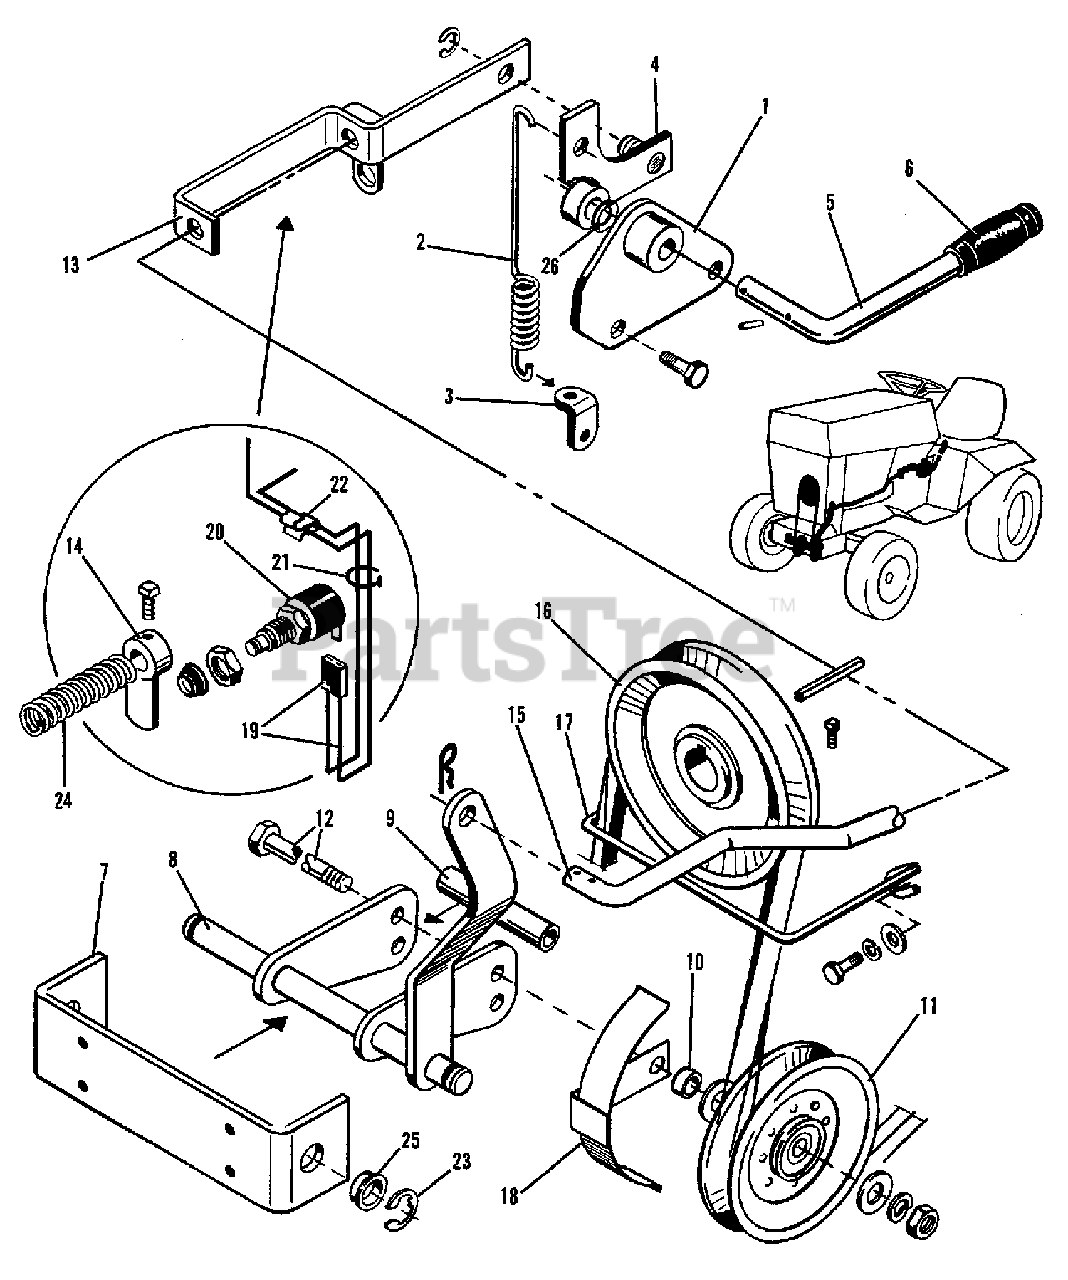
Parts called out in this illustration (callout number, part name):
1	BRACKET ASSEMBLY, P.T.O Clutch Arm
2	SPRING, Extension
3	CLIP, Spring
4	ARM ASSEMBLY, P.T.O. Clutch
4	RING, Snap
5	LEVER, Clutch, P.T.O.
5	PIN, Roll, 3/16 x 1
6	GRIP, Handle
7	BRACKET, Idler Support
7	CAPSCREW, 5/16 NC x 3/4
7	LOCKWASHER, 5/16
7	NUT, Hex, 5/16 NC
8	CLEVIS ASSEMBLY, P.T.O. Idler
9	SPACER, Idler
11	PULLEY, Idler
12	CAPSCREW, 3/8 NC x 6-1/4
12	WASHER, Plain, 7/16 x 1 x 14 Ga.
12	LOCKWASHER, 3/8
12	NUT, 3/8 NC
13	GUIDE ASSEMBLY, P.T.O. Control Rod.
14	STOP ASSEMBLY, P.T.O. Control Rod.
14	SETSCREW, 1/4 NC x 3/8, GR8
15	ROD, P.T.O. Control
16	SHEAVE, Front P.T.O.
16	KEY Parallel, 1/4 x 1/4 x 1-1/2
17	GUIDE, Belt (Front)
17	CAPSCREW, 3/8 NC x 3/4
17	LOCKWASHER, 3/8
17	WASHER, Plain, 7/16 x 1 x 14 Ga.
18	STOP ASSEMBLY, Belt
19	*LEAD, Manual P.T.O. Interlock Switch
20	*SWITCH, Momentary
20	*NUT, Hex, Special
20	*BOOT, Rubber
21	*TIE, Cable
22	*CLIP, Cable
23	RING, Snap
24	SPRING, Compression
24	WASHER, 17/32 x 1 x 20 Ga.
24	PIN, Quick
25	BUSHING, Nylon
26	WASHER, Spherical
